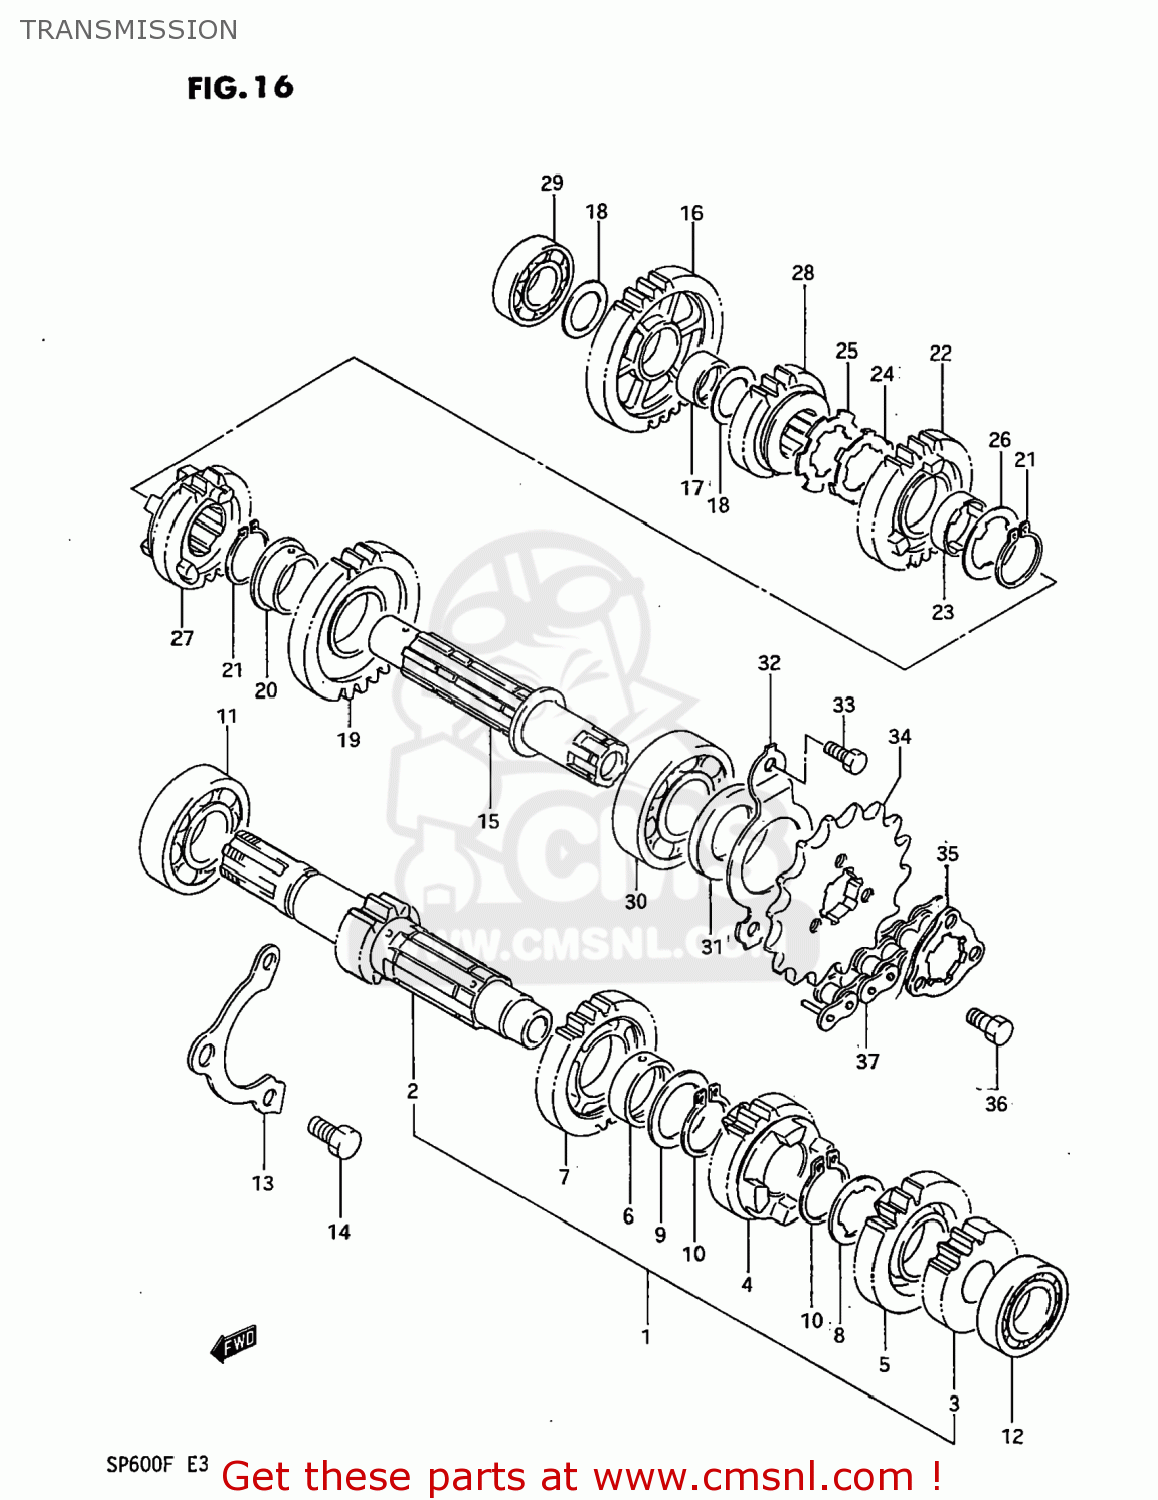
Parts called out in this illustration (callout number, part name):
1	SHAFT ASSEMBLY,COUNTER
2	SHAFT,COUNTER
3	GEAR,SECOND DRIVE
4	GEAR,THIRD/FOURTH DRIVE (NT:
5	GEAR,FOURTH DRIVE
6	BUSHING 25X29X10
7	GEAR,5TH DRIVE
8	WASHER,LOCK
9	WASHER
10	RING,SNAP
11	BEARING
12	BEARING
13	RETAINER,CNTR SHAFT BEARING
14	BOLT, 8X1.25X1
15	SHAFT,DRIVE
16	GEAR,FIRST DRIVEN
17	BUSH(20X24X13)
18	WASHER
19	GEAR,2ND DRIVEN
20	BUSH
21	RING,SNAP
22	GEAR,THIRD DRIVEN
23	BUSHING
24	WASHER
25	WASHER,LOCK
26	WASHER,LOCK
27	GEAR,FOURTH DRIVEN
28	GEAR,FIFTH DRIVEN
29	BEARING(20X42X12)
30	BEARING(25X62X17)
31	SEAL,OIL(25X45X5)
32	RETAINER,DRIVESHAFT O
33	BOLT
34	SPROCKET,ENGINE(NT:16)
35	PLATE,ENGINE SPROCKET
36	BOLT(6X13)
37	CHAIN ASSEMBLY,DRIVE
